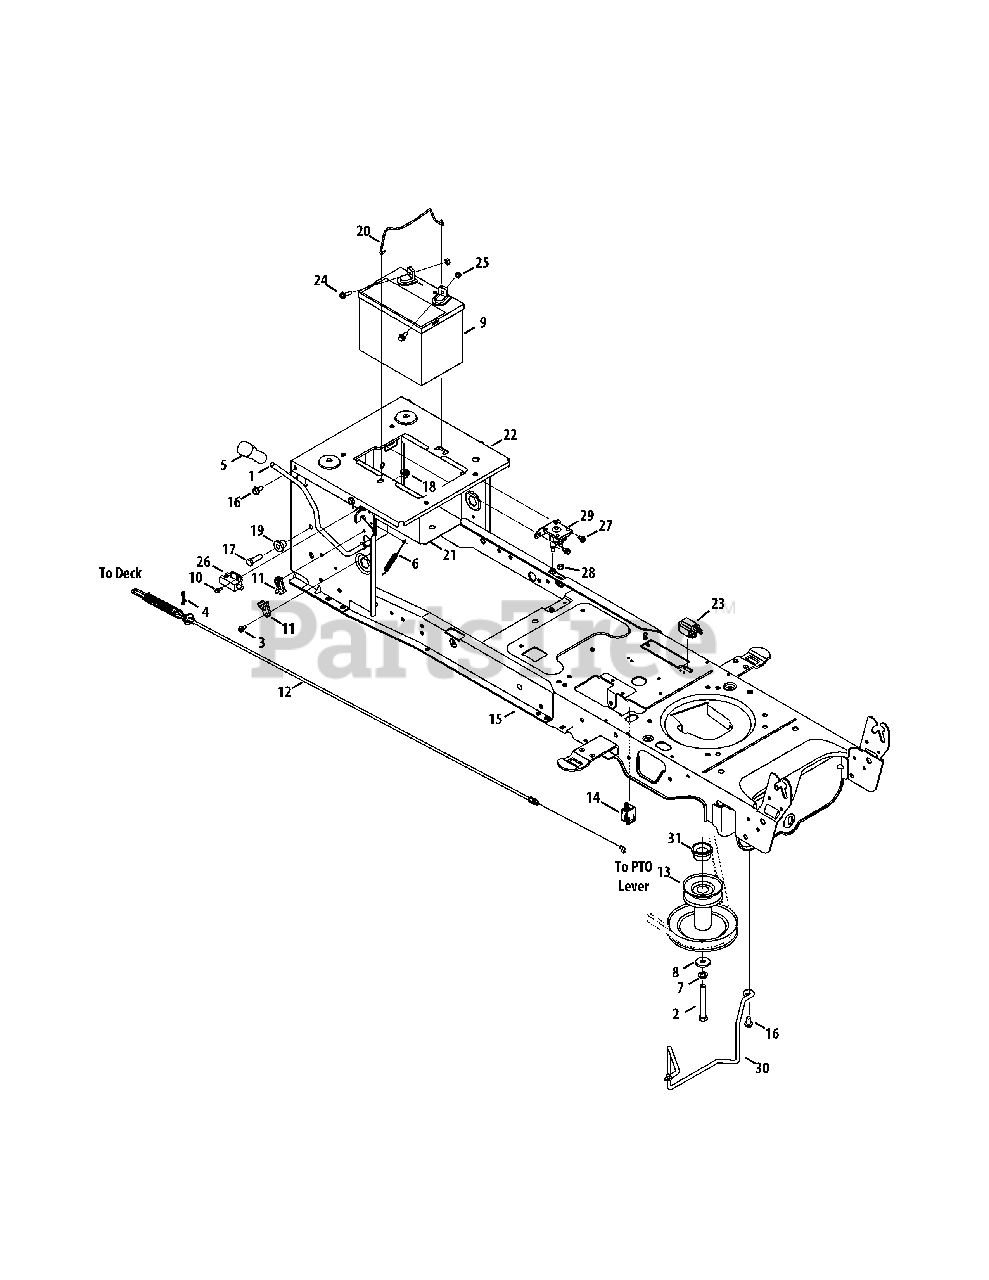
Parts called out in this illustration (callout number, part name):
1	Handle Ass’y, PTO
2	Hex Screw, 7/16-20, 3.50, Gr5
3	Screw, Self-tapping, 1/4-20, 0.50
4	Pin, Cotter, Bow-Tie 72
5	Grip, Handle, Cub
6	Spring, Ext, .38 Dia x 5.6
7	Washer, Lock, 7/16, Regular Duty
8	Washer, Flat, .450 x 1.250 x .164
10	Screw, Shoulder, #10-32, .500
11	Bearing, PTO
12	Cable, Engag, Deck
13	Pulley, Engine, 3.56 x 6.12 Dia.
14	Switch, Plunger, Snap Mount
15	Frame Ass’y, Lower
16	Screw, Self-tapping, 5/16-18, .750,
17	Hex Screw, 3/8-16, 1.25, Gr5, Std
18	Nut, Flange Lock, 3/8-16, Grf,
19	Spacer, Shoulder, .38 x 1.0 x .70
20	Rod, Battery
21	Tray, Battery
22	Bracket, Frame, Seat
23	Switch, 3-Pole
24	Hex Flange Screw, 1/4-20, .75, Gr5
25	Nut, Sems, 1/4-20
26	Switch, Interlock
27	Screw, Self-tapping, 1/4-20, 0.375,
28	Nut, Flange Lock, 1/4-20, Grf,
29	Solenoid, 12V, 100 Amp, 4 term
30	Rod, Keeper
31	Spacer, 1.010 x 1.40 x .825
